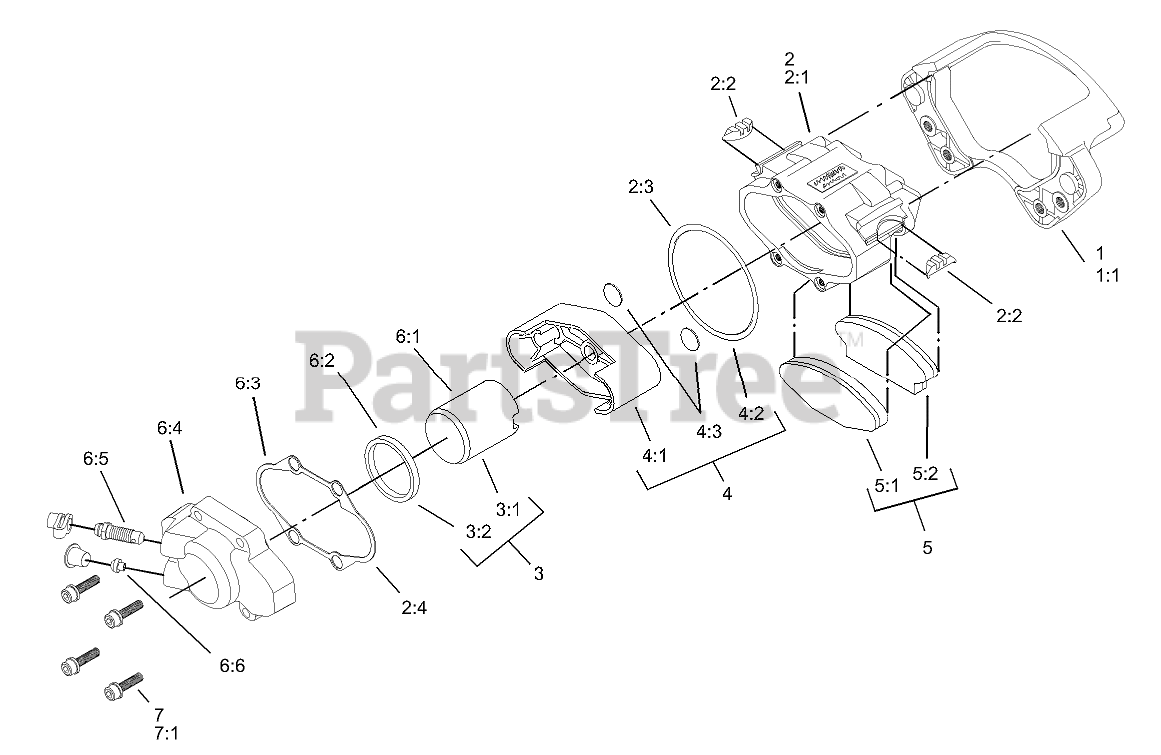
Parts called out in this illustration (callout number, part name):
1	BRACKET KIT
1:1	Bracket
2	HOUSING KIT
2:1	Housing
2:2	Spring-Rubber
2:3	Seal-Dust
2:4	Gasket
3	PISTON & SEAL KIT
3:1	Piston-Round
3:2	Seal-Square
4	PISTON & O-RING KIT
4:1	Piston-Oval
4:2	Seal-Dust
4:3	Plug-Piston
5	PAD KIT
5:1	Pad/Holder ASM
5:2	Pad/Holder ASM
6	LH PISTON & COVER ASM KIT
6:1	Piston-Round
6:2	Seal-Square
6:3	Gasket
6:4	Cover
6:5	Screw-Bleeder
6:6	Insert-Seat
7	BOLT KIT
7:1	Screw-Cover
